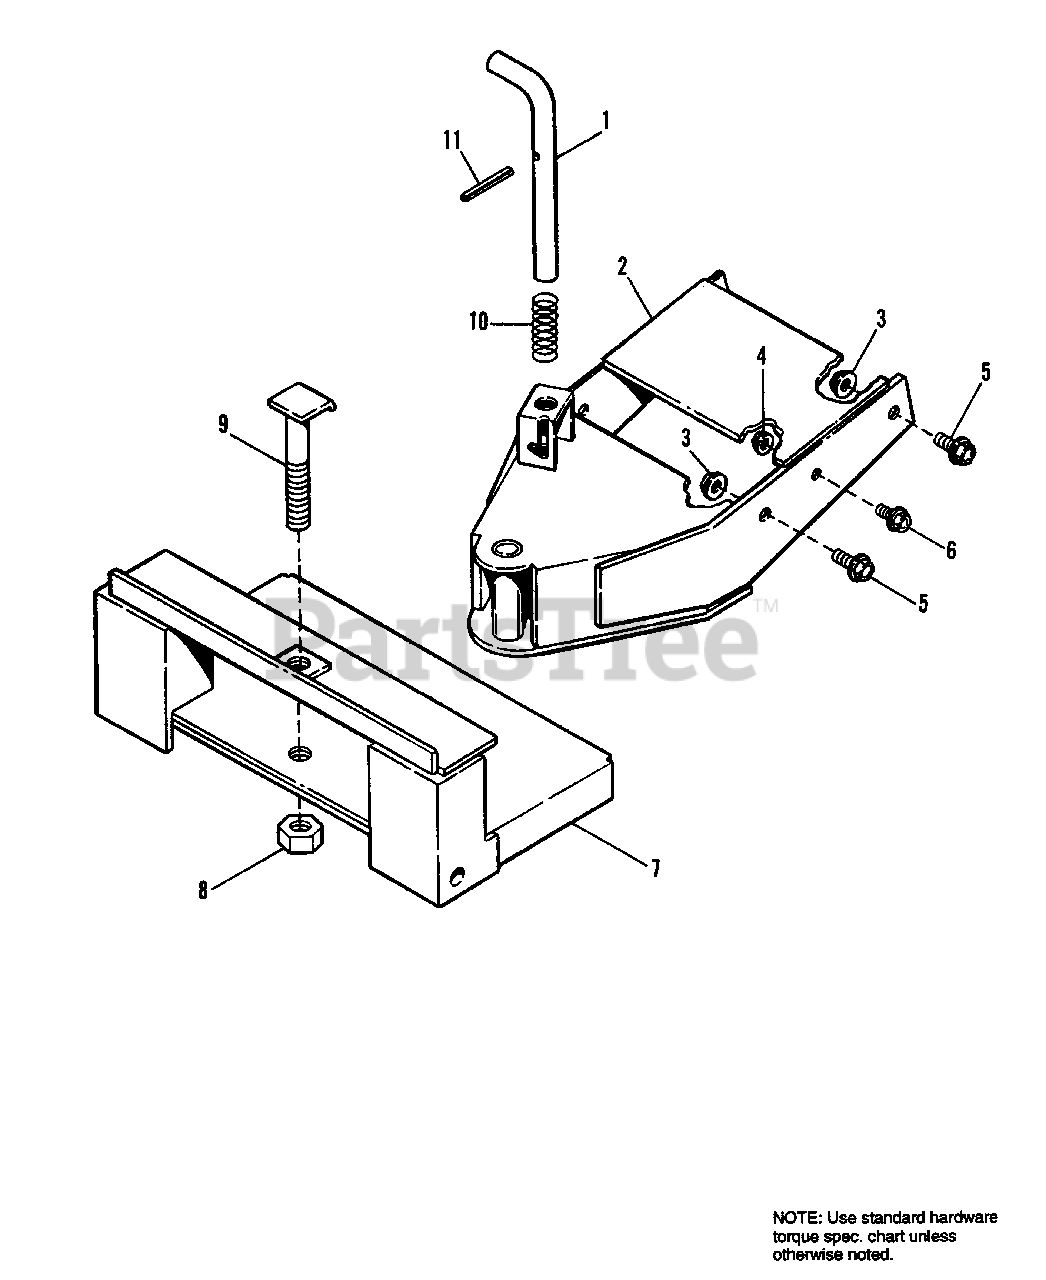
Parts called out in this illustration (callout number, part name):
1	PIN, Lock
3	NUT, Hex Flange Whizlock 7/16-14
4	NUT, Hex Flange Whizlock, 5/16-16
5	CAPSCREW, Hex Whizlock, 7/16-14 x 1
6	CAPSCREW, Hex Whizlock, 3/8-16 x 1
7	PLATE, Pivot
8	NUT, Hex, 3/4-10
11	PIN, Spring 1/4 x 2-3/4
